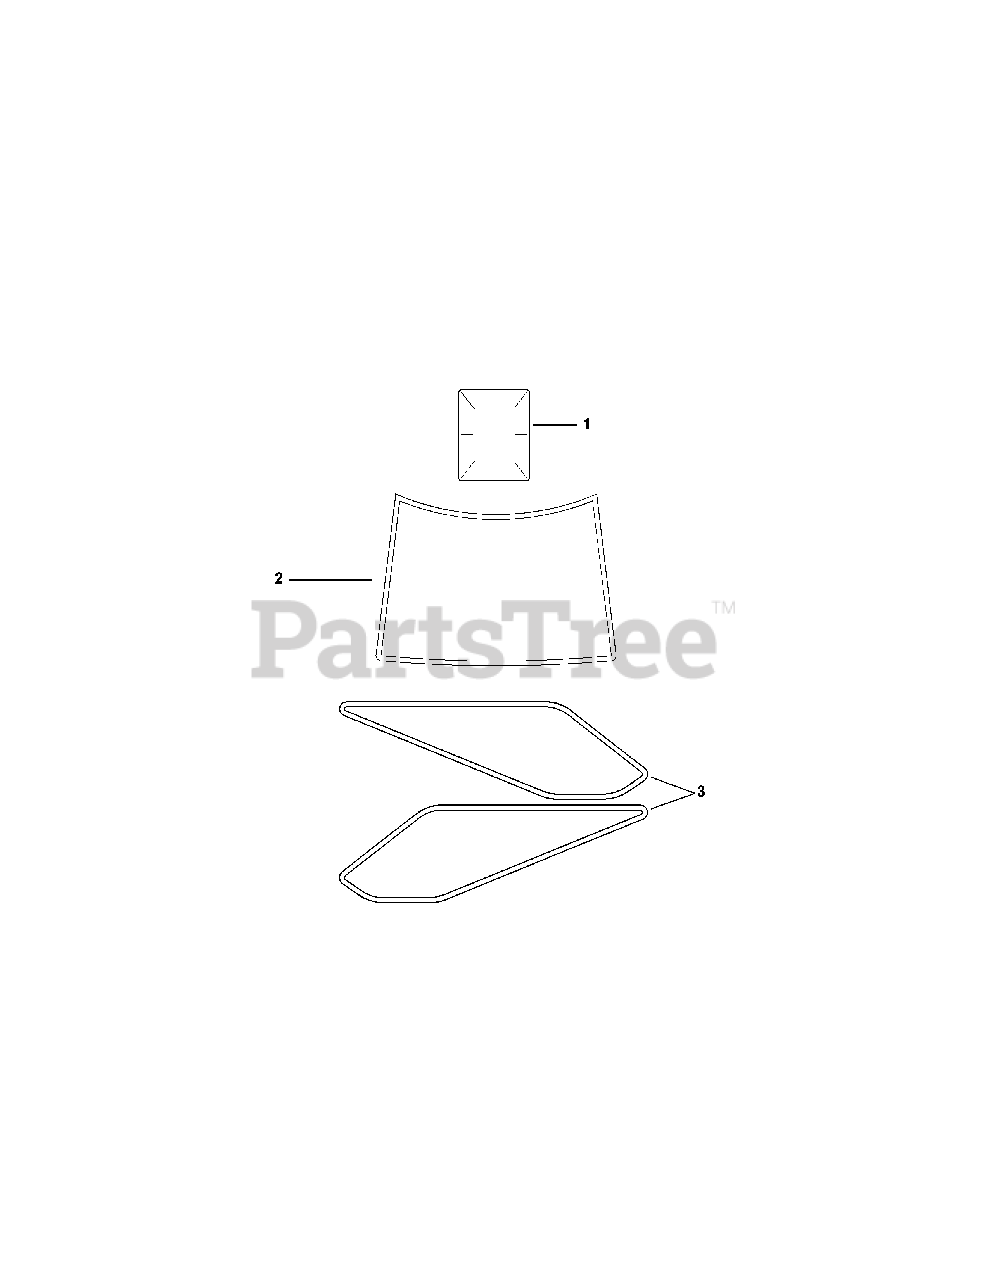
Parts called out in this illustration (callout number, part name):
1	Clear Laminate Decal
2	Decal, 22 HP
3	Decal, Twin Wings
